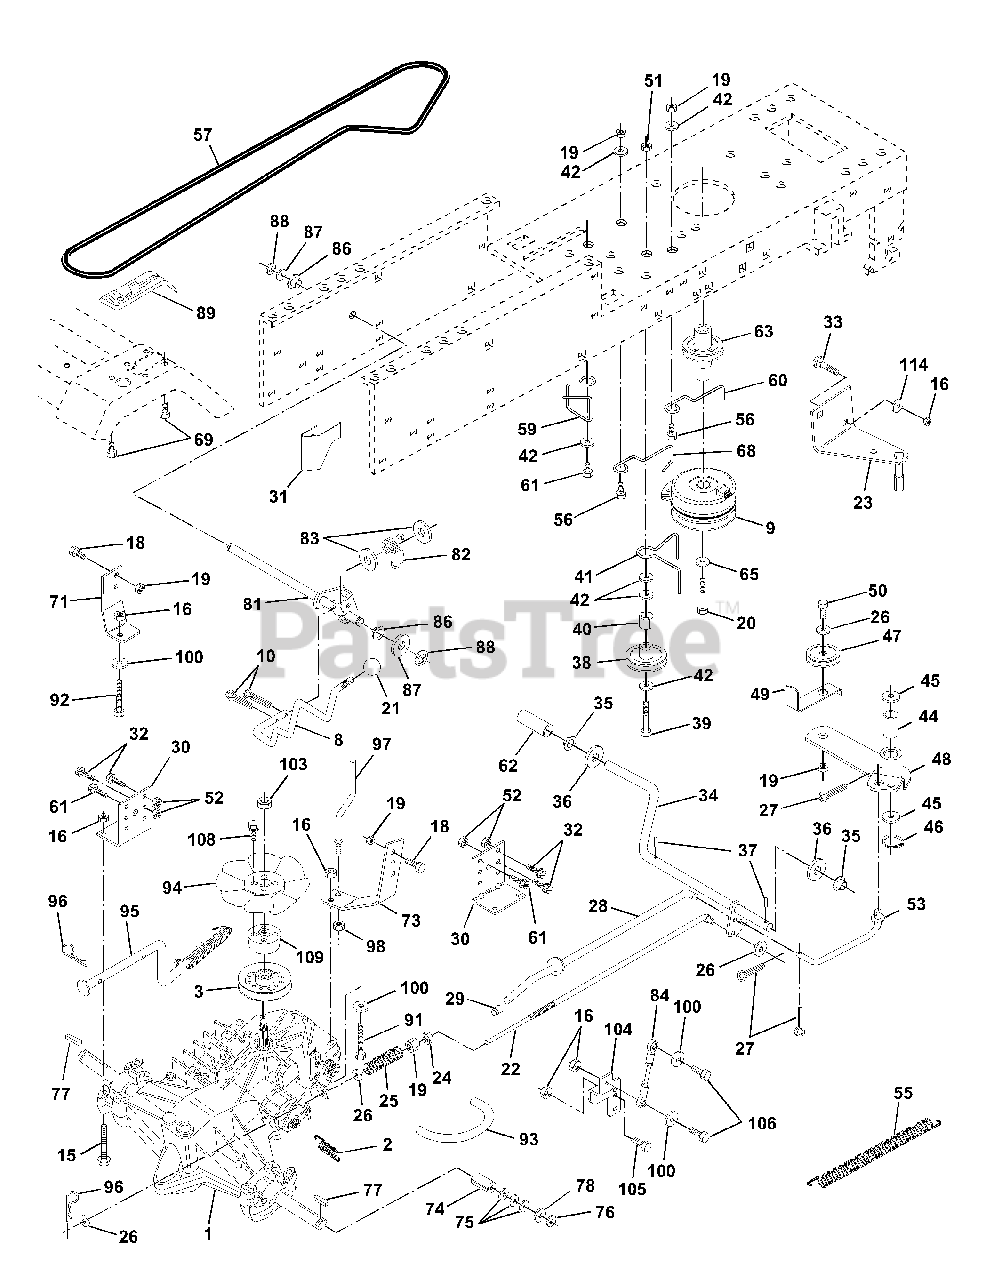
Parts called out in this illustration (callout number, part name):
1	Transaxle Assembly 1-5/8 TT
2	Spring, Return, Brake
3	Pulley, Transaxle
8	Rod Shift Fender LT
9	Clutch, Elect. EVX LT Mag 5217-2
10	Pin Cotter 1/8 x 1 CAD
15	Bolt Fin Hex 5/16-18 Unc
16	Nut Lock Hex W/Ins. 5/16-18 Unc P
18	Bolt Fin Hex 3/8-16 Unc x 1 Gr. 5
19	Nut Lock Hex W/Wsh 3/8-16 Unc
20	Bolt Hex 7/16-20 x 4-1/4 Ga. 5
21	Knob, Duckhead 1/2-13
22	Rod, Brake Hydro
23	Bracket, Asm Clutch Mtg EVX
24	Nut
25	Spring, Brake Rod
26	Washer
27	Pin Cotter 1/8 x 3/4 CAD.
28	Rod, Parking Brake
29	Cap, Parking Brake
30	Bracket, Transaxle
31	Keeper Belt Lh
32	Bolt Hex Hd 5/16-18 Unc x 3/4
33	Bolt Rdhd Sqnk 5/16-18 UNC x 3/4
34	Shaft, Foot Pedal
35	Bearing, Nylon
37	Pin, Roll
38	Pulley, Idler, Flat
40	Spacer, Split
41	Keeper, Belt Retainer
42	Washer 13/32 x 13/16 x 12 Gauge
44	Bearing, Nylon
45	Washer, Hardened
46	Ring, Klip
47	Pulley, Idler, V-Groove
48	Bellcrank Assembly
49	Retainer, Belt
50	Bolt
52	Nut Crownlock 5/16-18
53	Link, Clutch
55	Spring, Return, Clutch
56	Bolt Fin Hex 3/8-16 UNC x 1-1/4
57	V-Belt, Ground Drive
59	Keeper, Center Span
60	Keeper Belt Engine
61	Screw Thdrol. 3/8-16 x 3/4 Ty. TT
62	Cover, Pedal
63	Pulley, Clutch Electric EVX
65	Washer
68	Keeper Belt Engine
71	Strap Torque Lh Hydro
73	Strap Torque Rh Hydro
74	Spacer, Split
75	Washer 25/32 x 1-1/4 x 16 Gauge
77	Key, Square
78	Washer 25/32 x 1-5/8 x 16 Gauge
81	Shaft Asm. Cross Hydro
82	Spring Torsion T/A
83	Washer 17/32 x 3/4 x 16 Ga.
84	Rod, Tie Hydro
86	Bushing Rod Steering 629/632 ID
87	Washer 21/32 x 1-1/4 x 16 Ga.
88	Ring Klip #5304-62
89	Console, Shift
91	Bolt Fin Hex 5/16-18 x 2-1/4
92	Bolt Fin Hex 5/6-18 Unc x 1-1/2
93	Line Fuel Hydro 4"
94	Fan, Hydro 7"
95	Control Asm Bypass Hydro
96	Retainer Spring 1" Zinc/Cad
97	Keeper Belt Rh Hydro
98	Nut Keps Hex 3/8-16 Unc
100	Washer 11/32 x 3/4 x 16 Ga.
103	Nut Nylon Insert 1/2-20 Unf.
104	Arm, Control Hydro
105	Screw Cap Hex 5/16 x 18 x 1
106	Bolt Fin Hex 5/16-18 Unc x 1-1/4
108	Screw Hex Wh Hd #10-24 x
109	Adaptor Fan Hydro LT Hyd Alum
114	Washer 11/32 x 3/4 x 14 Ga.
